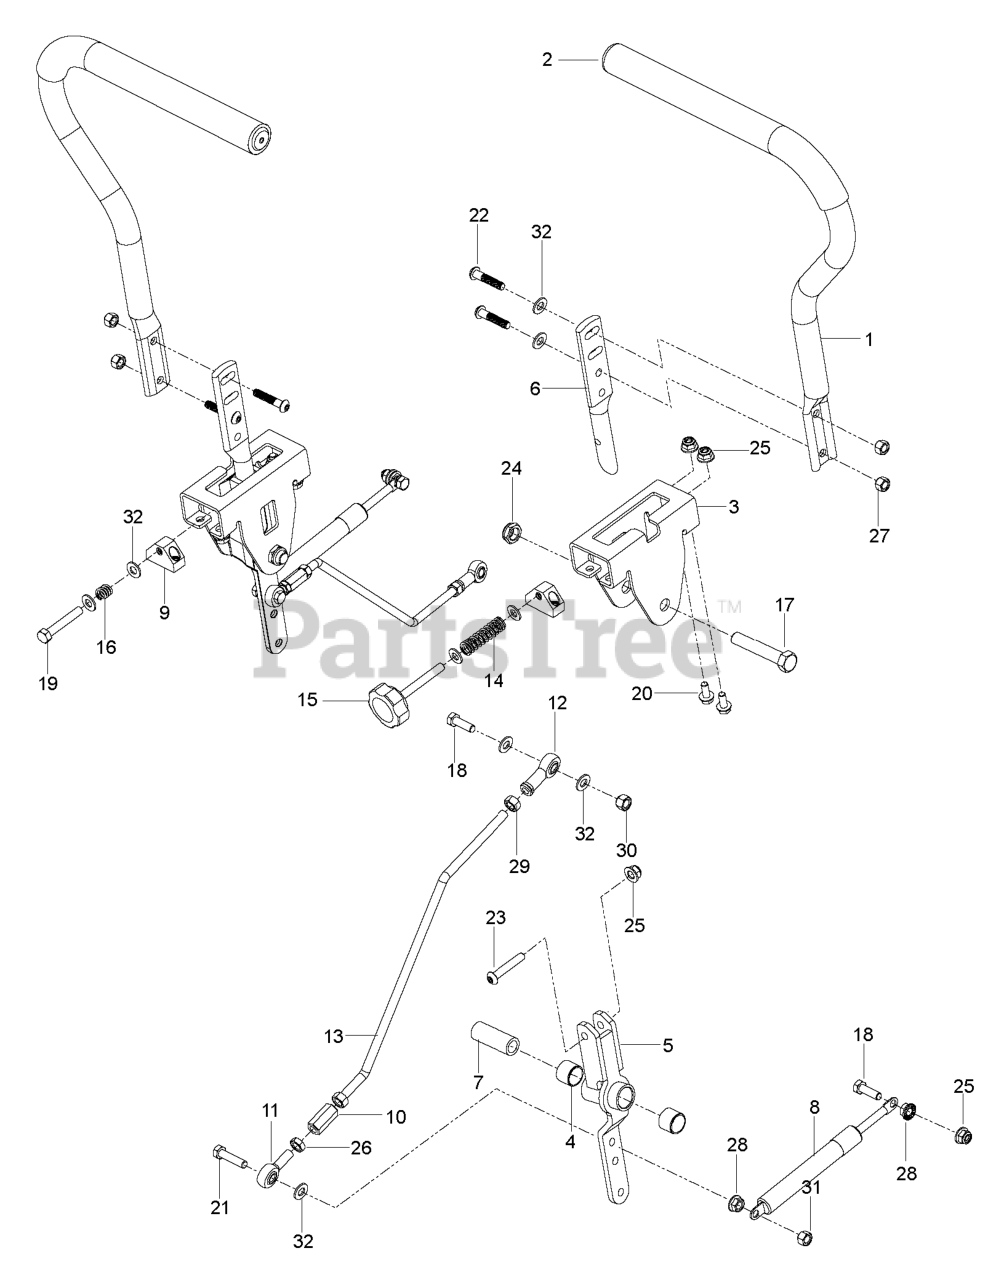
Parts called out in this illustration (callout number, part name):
1	LEVER.ASSY.CTRL.TBE.RZ.HIGHFLT
2	GRIP, DRIVE LEVER
3	BRACKET.CONTROL.NARROWSLOT.BLK
4	BEARING
5	CONTROL.WELDMENT.RZ
6	LEVER.HANDLE MOUNT
7	SPACER.PIVOT.CONTROL
9	BLOCK TRACKING CONTROL ZTR
10	ROD END COUPLER
11	RP.ROD.END.LH
12	RH ROD END
13	ROD MOTION CONTROL
14	SPRING COMPRESSION 2.0
17	HCS 1/2-13 X 2-3/4 GD 5 ZD
18	BOLT.FIN.HEX.5/16-18UNC X 1.00
19	HEX BOLT
20	HHFS 5/16-18 X 3/4
22	SCREW.BUTTHEAD.5/16-18X1-1.25
23	SCREW 5/16-18 X 1 3/4 BTN-HD
24	NUT 1/2-13 HEX JM NYL
25	5/16-18 NYLOC FLANGE NUT
26	NUT 5/16F LEFTHAND
27	NYLOCK.NUT.5/16-18 BLACK
28	NUT 5/16C WHIZ
30	5/16-18 THIN PROF NY
31	NUT.71038.31-18.HEX.NYLOCK
32	WASHER
